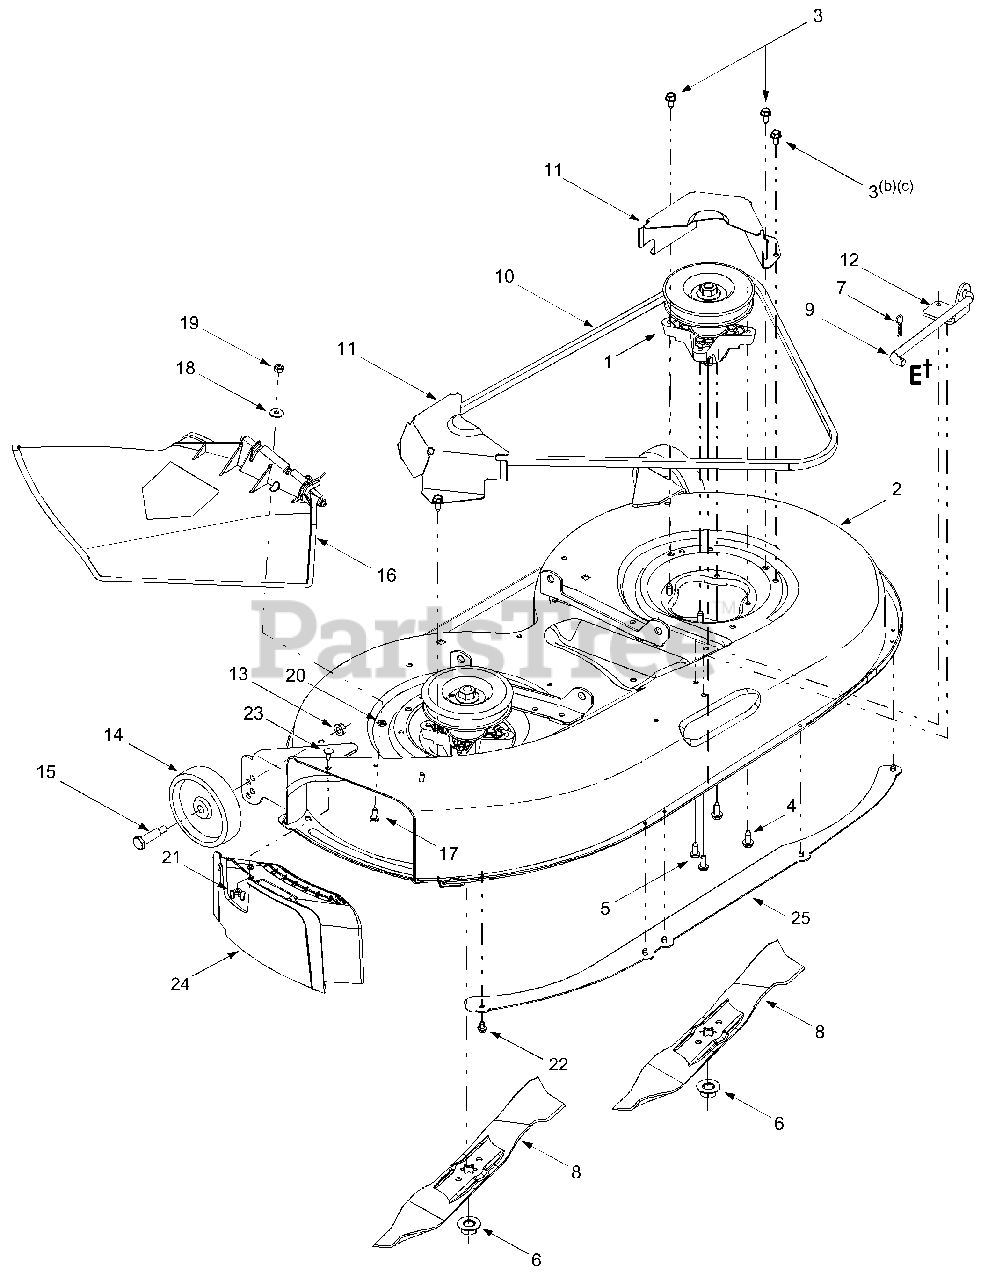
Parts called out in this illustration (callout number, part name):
1	Spindle Assembly
4	Screw, 5/16-18 x .75
5	Self-tapping Screw, 5/16-18 x .75
6	Hex Flange Nut, 5/8-18
7	Internal Cotter Pin, .080 x 1.56
8	Blade, 19.38"
8	Blade, 21.23"
9	Deck Hanger Link/Anti-sway Rod
10	Deck Belt
13	Flange Lock Nut, 3/8-16
14	Deck Wheel, 5 x 1.38
15	Shoulder Screw, .498 x 1.53
16	Discharge Chute Assembly
17	Hex Cap Screw:1/4-20 x .620
18	Bell Washer, .265 x .75 x .062
19	Hex Nut, 1/4-20
20	Push Nut, 1/4
21	Wing Nut, 1/4-20
22	Self-tapping Screw, 1/4-20 x .5
23	Carriage Screw, 1/4-20 x .62
24	Mulch Plug
